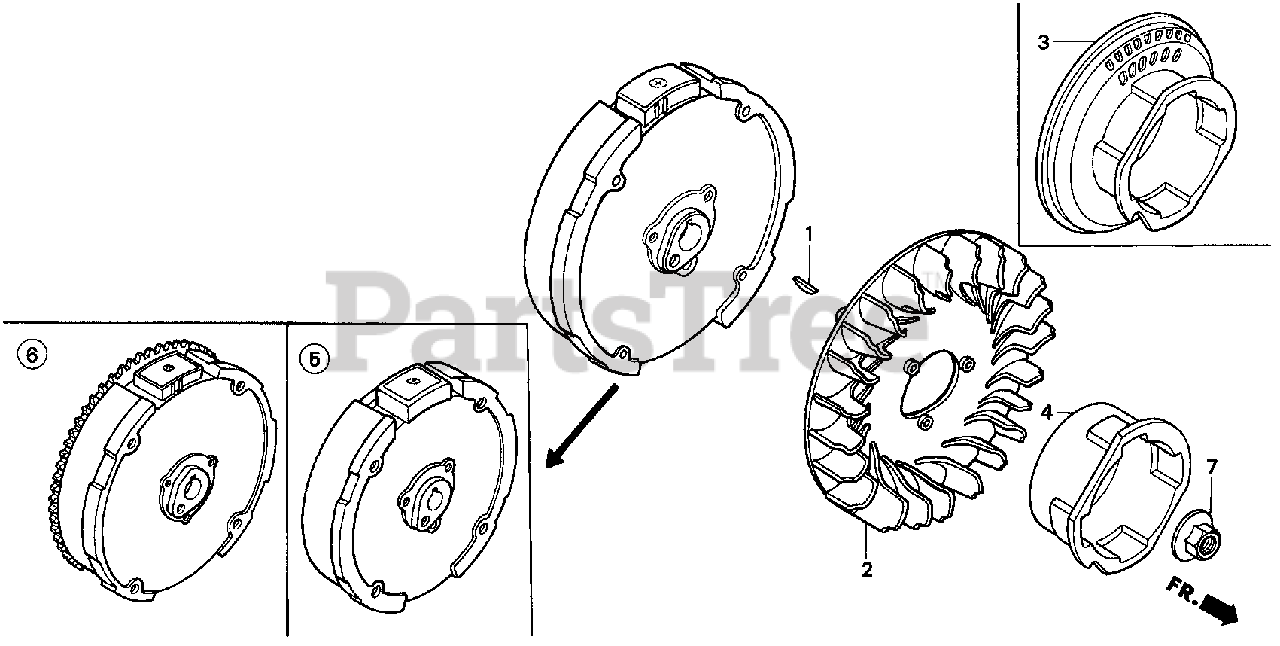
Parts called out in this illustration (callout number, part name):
1	KEY, SPECIAL WOODRUFF (25X18)
2	FAN, COOLING
4	PULLEY, STARTER
5	FLYWHEEL (LAMP)
7	NUT, SPECIAL (14MM)
